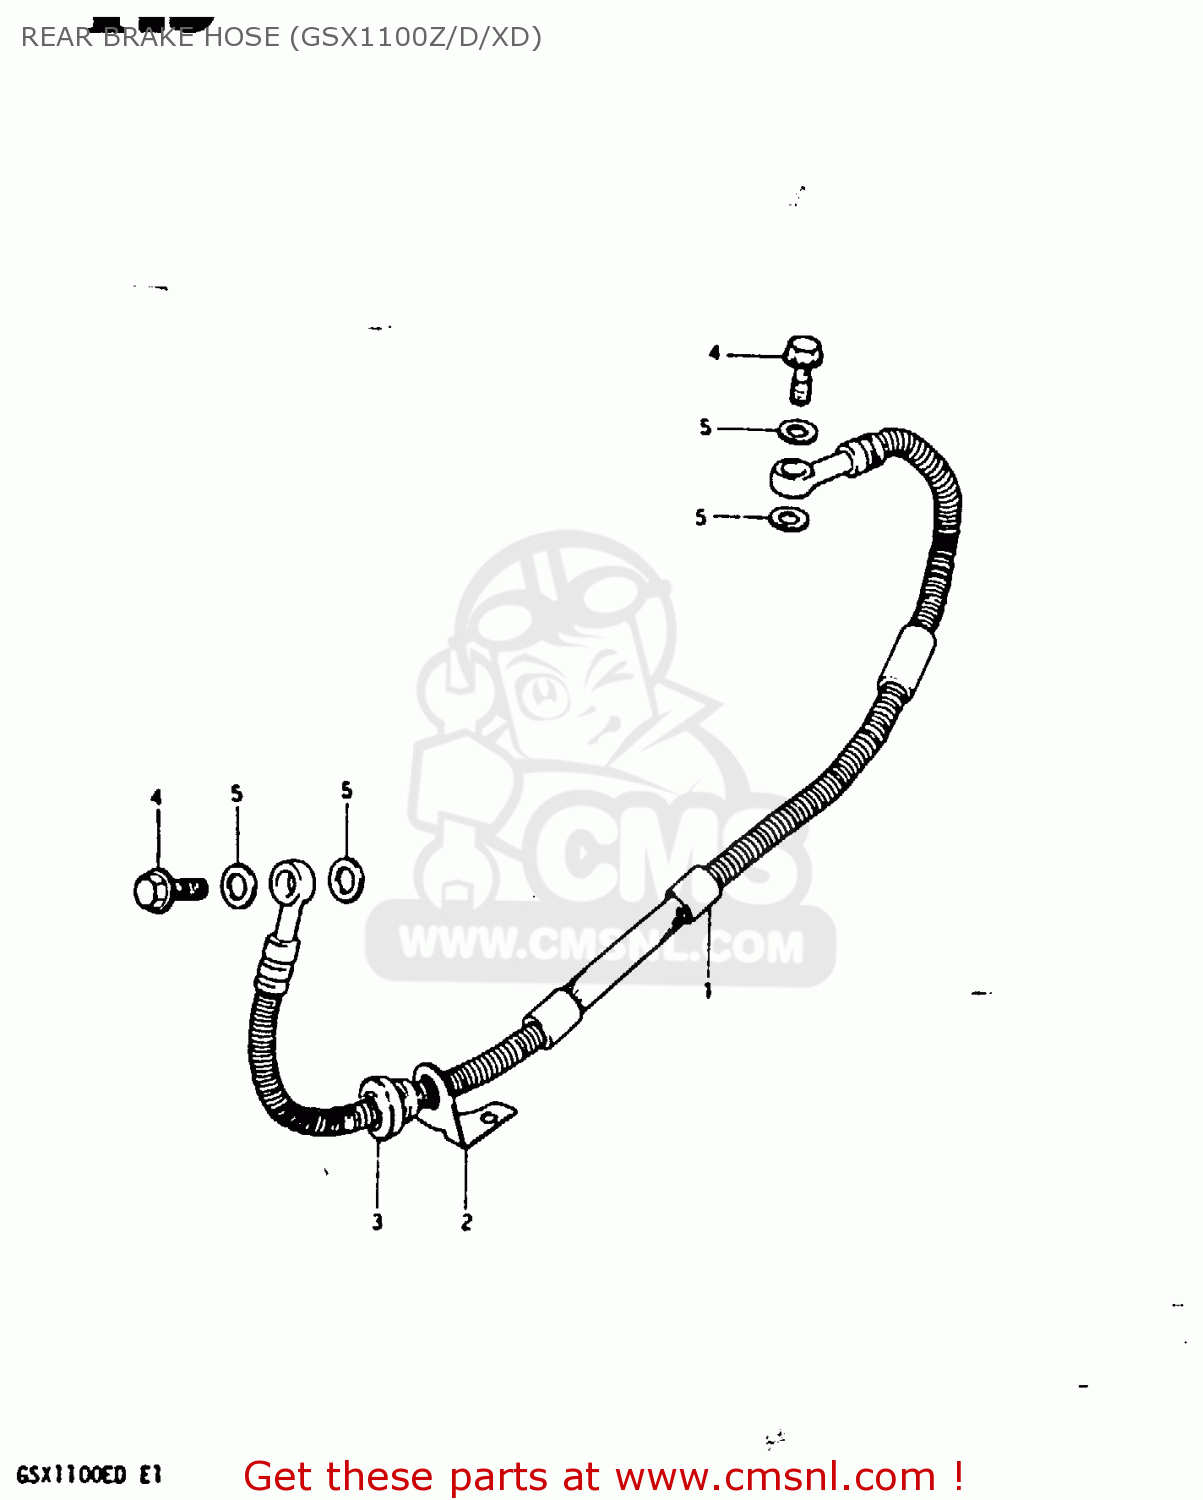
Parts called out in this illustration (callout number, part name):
1	HOSE,REAR BRAKE
2	GUIDE,BRAKE HOSE
3	GROMMET,BRAKE HOSE GUIDE
4	BOLT UNION
5	WASHER
